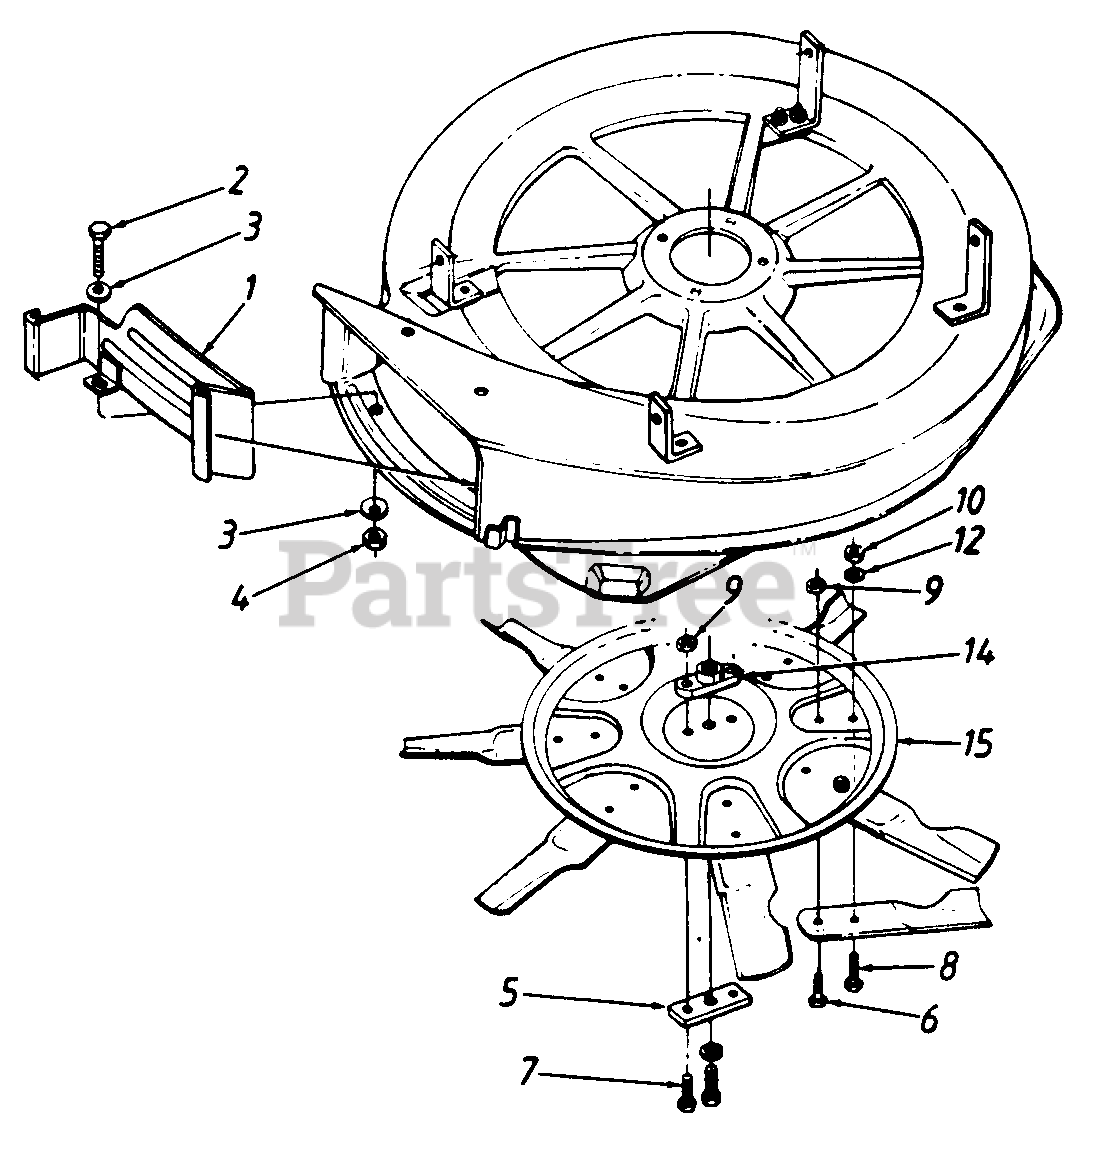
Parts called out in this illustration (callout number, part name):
1	Mulching Baffle Ass'y.
2	Hex Bolt 5/16-18 x .5"
3	Bell-Wash. .325" I.D.
4	Hex L-Nut 5/16-18 Thd.
7	Hex Bolt 5/16-24 x 1 .25" Lg. (Gr. 5)
8	Hex Bolt 3/8-24 x .88 Lg.
9	Hex L-Nut 5/16-24 Thd.
10	Hex L-Nut 3/8-24 Thd. (Gr.5)
12	Fl-Wash. .406" I.D. x .75"
14	Blade Adapter
15	30 Mulching Blade Disc
